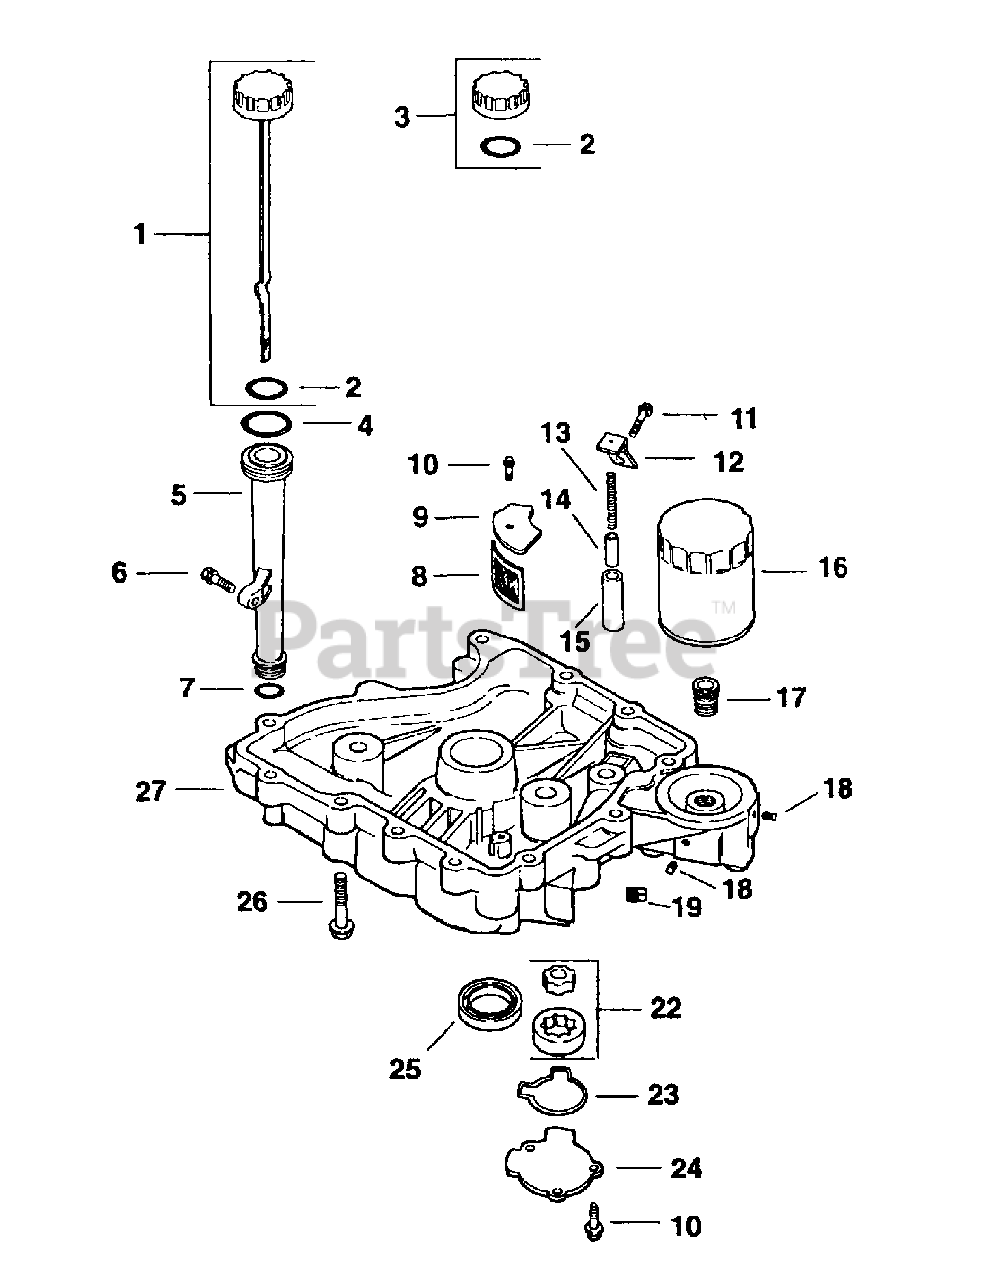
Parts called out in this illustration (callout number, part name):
1	Dipstick Assembly
2	O-Ring, Dipstick
3	Oil Fill Cap Kit
4	O-Ring, Oil Fill Tube (upper)
5	Tube, Oil Fill
6	Screw, Hex Flange
7	O-Ring, Oil Fill Tube (lower)
8	Screen, Oil Pick-Up
9	Cover, Oil Pick-Up Screen
10	Screw, Hex Flange
11	Screw, Hex Flange
12	Bracket, Oil Pump Relief
13	Spring, Oil Pump Relief Valve
14	Piston, Oil Pump Relief Valve
15	Body, Oil Pump Relief Valve
16	Filter, Oil
17	Adapter, Oil Filter
18	Plug, Sq. hd. Solid 1/8" N.P.T.F.
19	Plug, Sq. hd. Solid 3/8" N.P.T.F.
22	Pump, Oil
23	O-Ring, Oil Pump Cover
24	Cover, Oil Pump
25	Seal, Oil (PTO End)
26	Screw, Hex Flange
